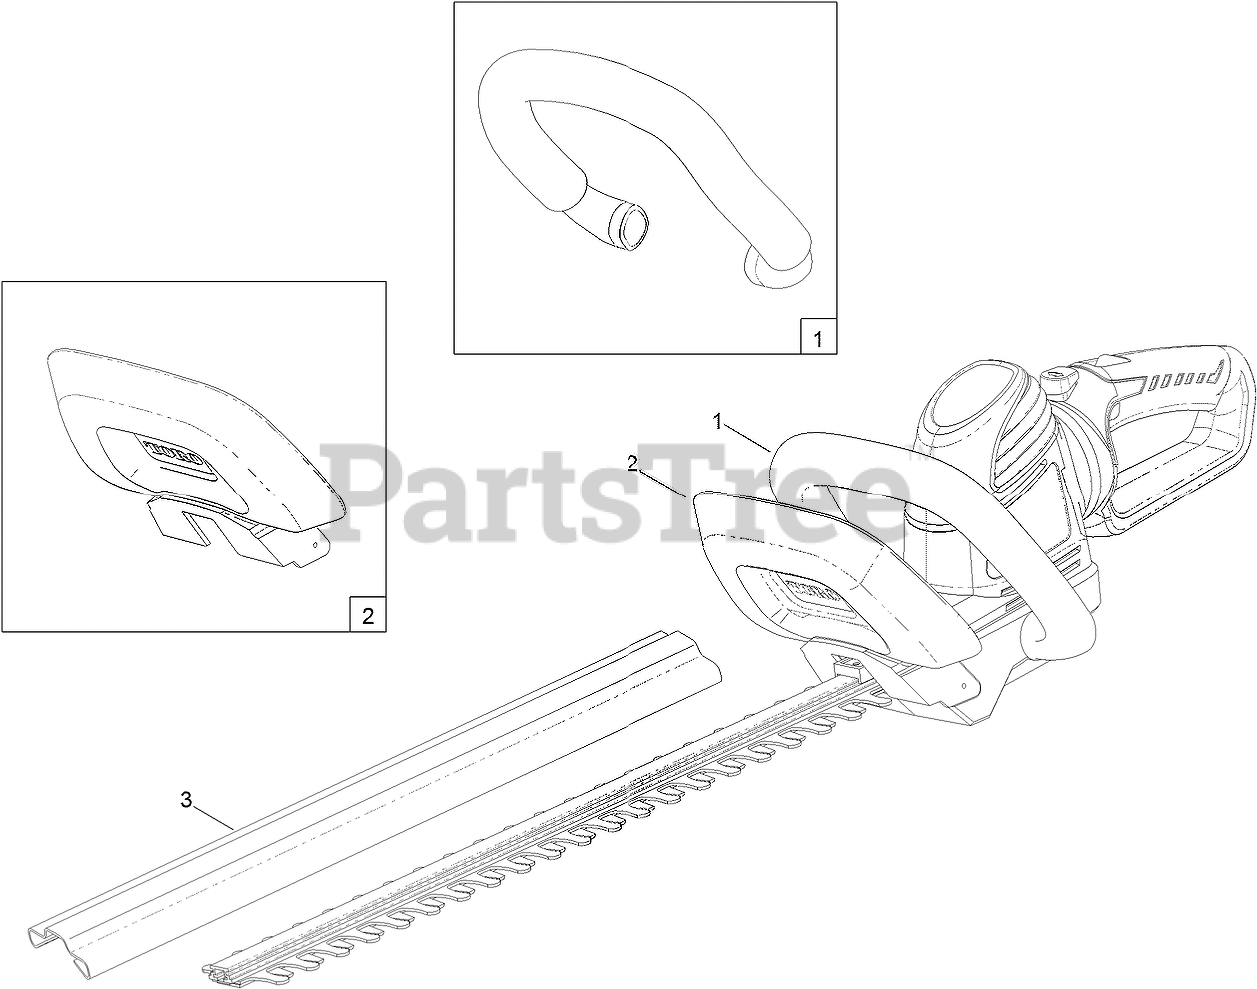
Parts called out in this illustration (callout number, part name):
1	HANDLE-ASSIST
2	GUARD ASM
3	SHEATH-BLADE
